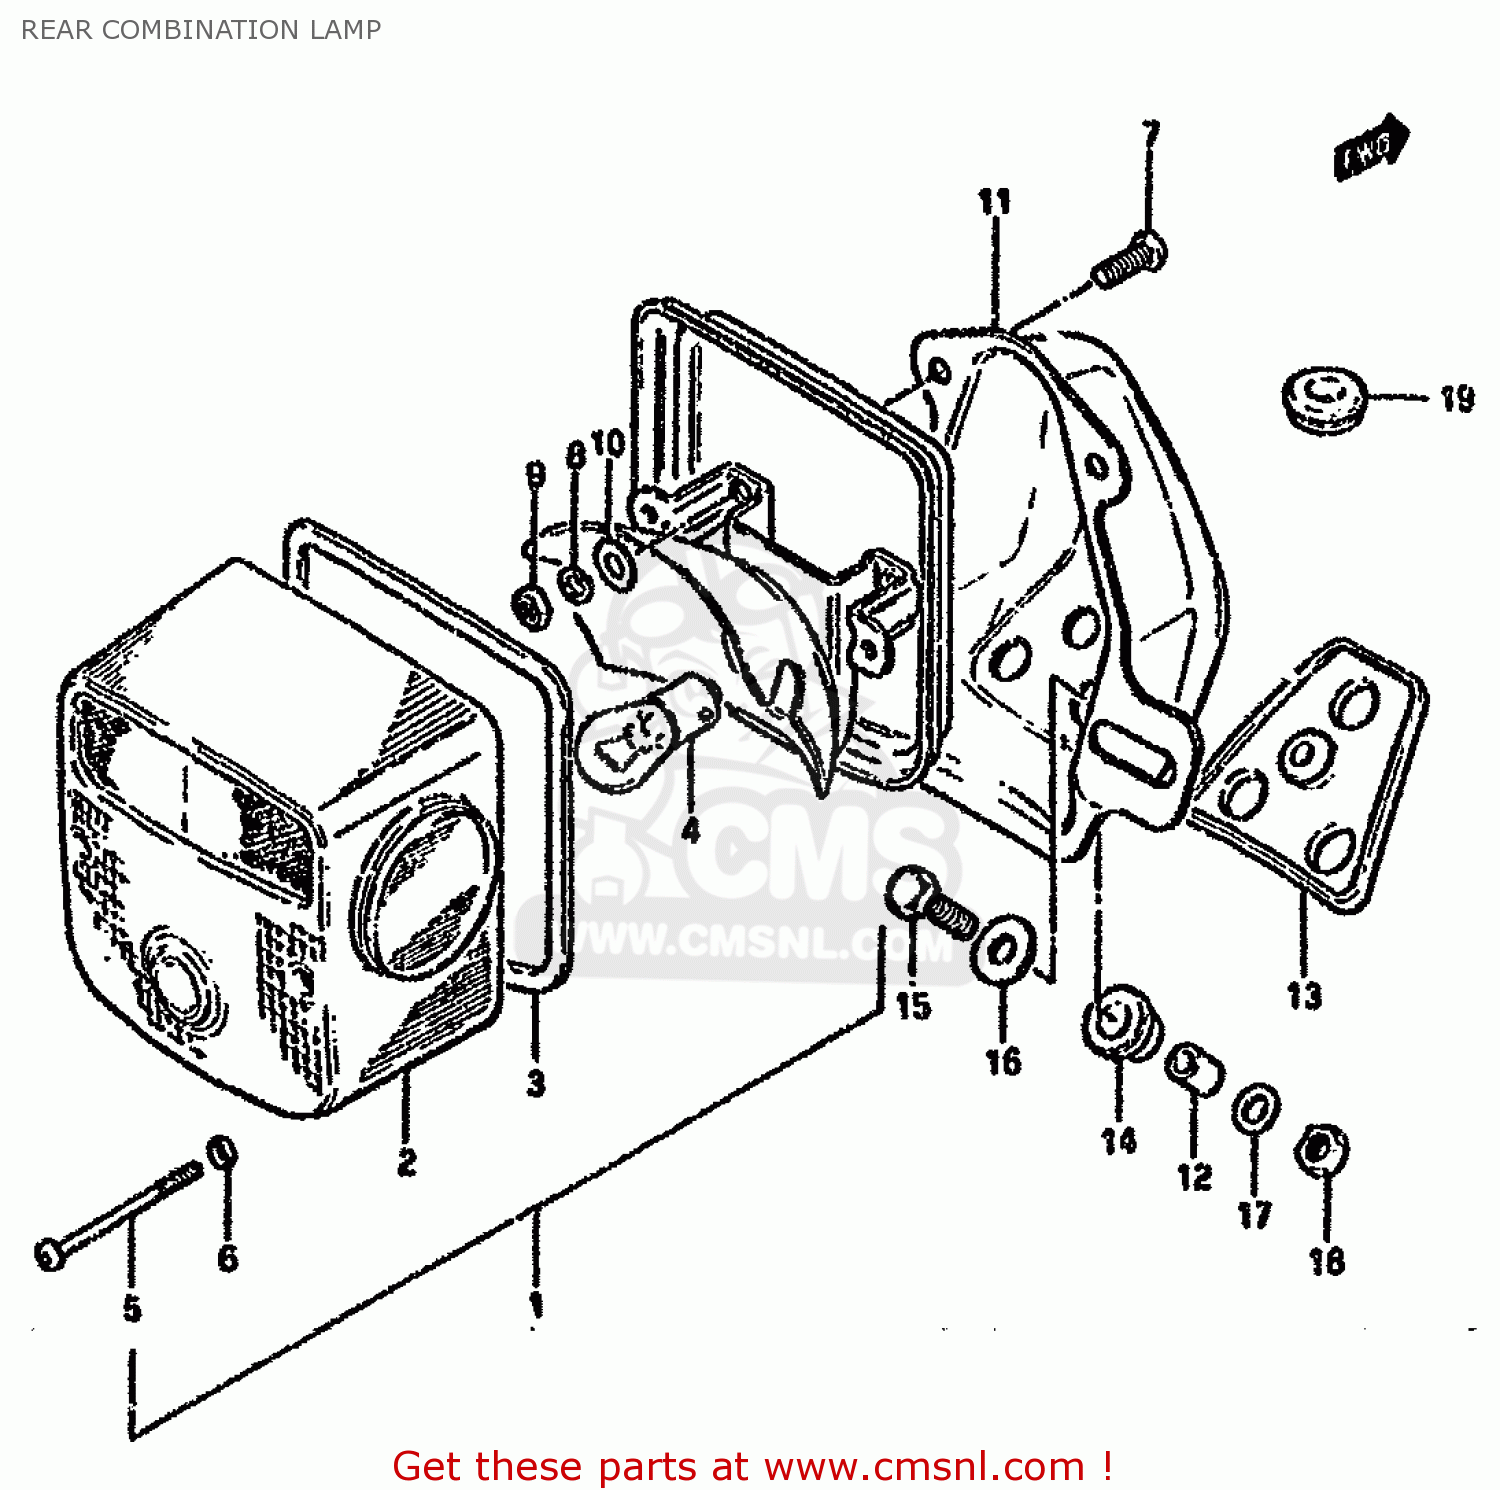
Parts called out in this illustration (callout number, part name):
1	LAMP UNIT,TAIL
2	LENS
3	GASKET (NAS)
4	BULB(12V23W)
5	SCREW (4X55)
6	GASKET (NAS)
7	SCREW
8	LOCK WASHER
9	NUT 5MM
10	WASHER
11	BRACKET UNIT,TAIL LAMP
12	SPACER
13	CUSHION
14	CUSHION
15	BOLT
16	WASHER (6.5X20X1.2)
17	WASHER, LOWER
18	NUT
19	GROMMET
